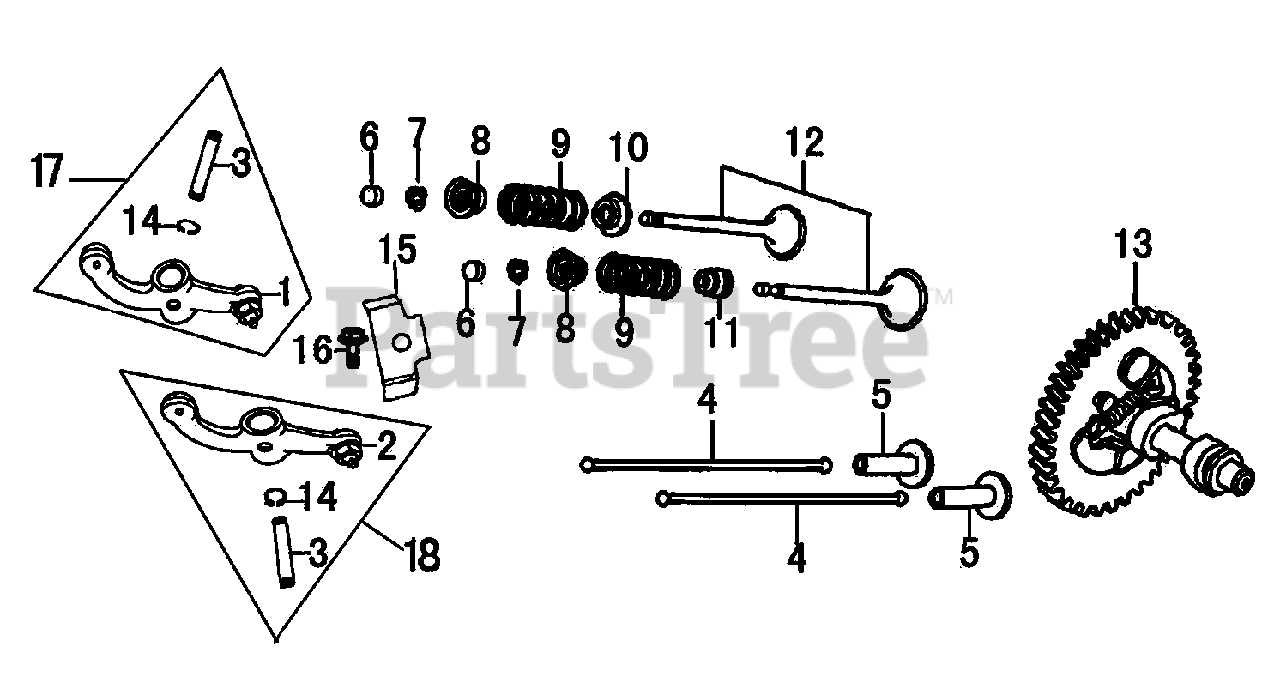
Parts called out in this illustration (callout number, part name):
1	ROCKER ARM EXH.
2	ROCKER ARM INT.
3	VALVE ROCKER SHAFT
5	LIFTER, VALVE
6	ROTATOR, VALVE
7	LOCKER, VALVE
8	RETAINER, VALVE SPRING
9	SPRING, VALVE
10	SEAT, VALVE SPRING
11	SEAL, VALVE STEM
12	VALVE ASSY.
13	CAMSHAFT ASSY
15	RETAINER, ROCKER ARM SHAFT
16	BOLT, FLANGE
17	ROCKER ARM ASSY. EXHAUST
18	ROCKER ARM ASSY. INTAKE
